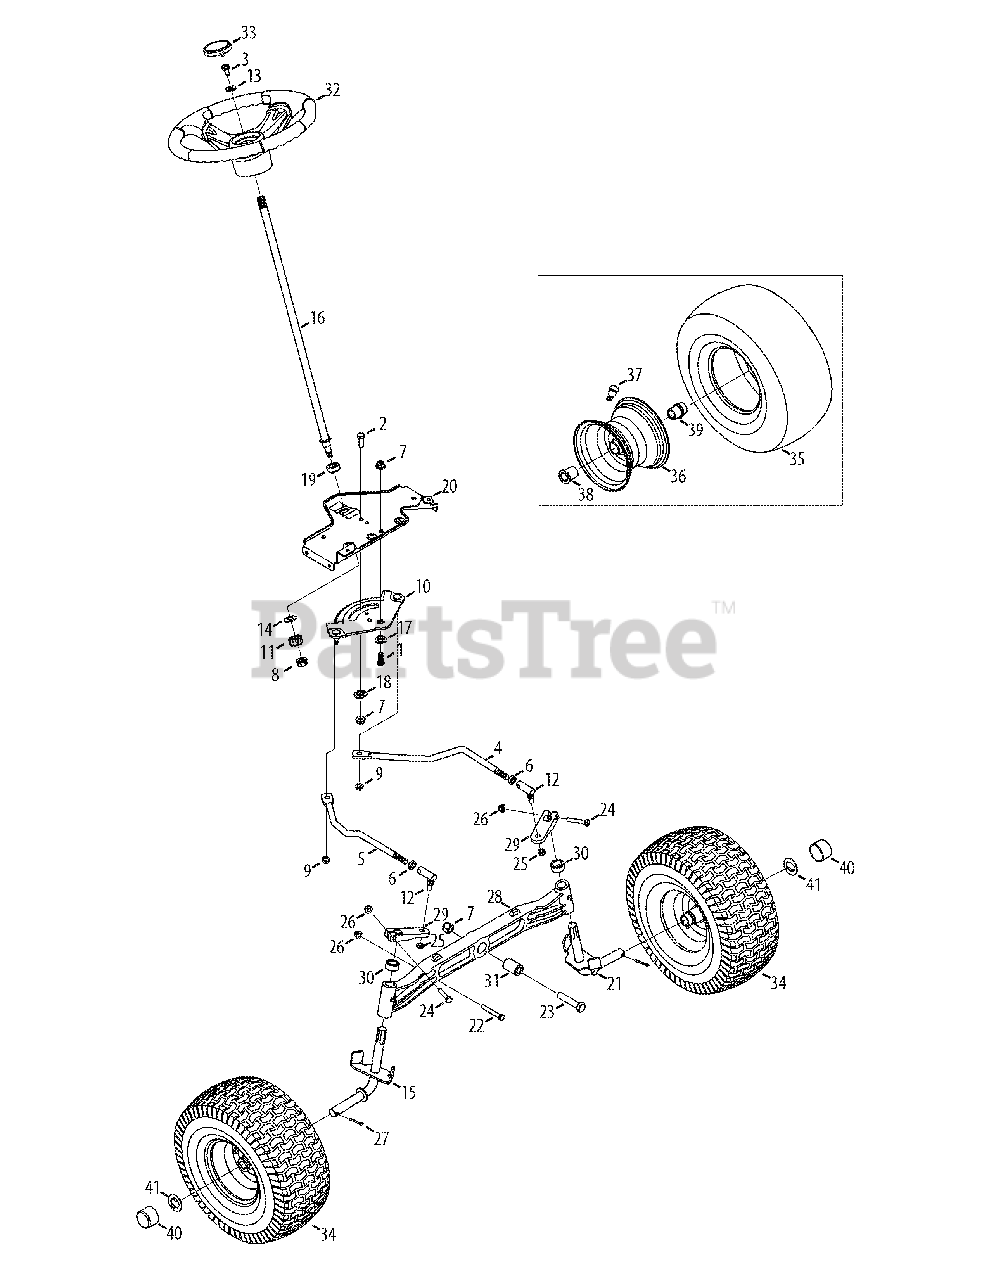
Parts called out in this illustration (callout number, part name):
1	Hex Screw, 3/8-16, 1.00, Gr5, Spec
2	Hex Screw, 3/8-16, 1.00, Gr5, Std
3	Hex Screw, 5/16-18, 1.00, Gr5, Lock
4	Link, Drag LH
5	Link, Drag RH
6	Nut, Jam, 7/16-20, Gr2
7	Nut, Flange Lock, 3/8-16, Grf,
8	Nut, Flange Lock, 7/16-20, Grb, Lock
9	Nut, Flange Lock, 5/16-18, Gr5, Sd Lk
10	Gear, Steering, 11/90 Ratio
11	Gear, Pinion, Steering
12	Ball Joint, 7/16-20, Lock
13	Washer, Flat, .406 x .875 x .105
14	Washer, Flat, .51 x 1.12 x .06
15	Axle Ass’y, RH .750 Dia (46" Deck)
16	Shaft, Steering, .625 OD x 24.25
17	Spacer, Shoulder, .385x 1.25 x .3025
18	Spacer, .38 x 1.375, Special
19	Bearing, Flange, Hex 5/8 Pm
20	Bracket, Support, Steering
20	Screw, .750 5/16-18
21	Axle Ass’y, LH .750 Dia (46" Deck)
22	Hex Screw, 5/16-18, 2.25, Gr5, Std
23	Hex Screw, 3/8-16, 2.50, Gr5, Std
24	Hex Screw, 5/16-18, 1.75, Gr5, Std
25	Nut, Hex Lock, 3/8-24, Grb
26	Nut, Flange Lock, 5/16-18, Grf
27	Pin, Cotter, 5/32, 1.25
28	Axle, Pivot Bar, Cast
29	Steering, Block
30	Spacer, .71 ID x .125 OD x .56
31	Spacer, .385 x 1.00 x 1.5075
32	Steering Wheel
33	Cap, Sprig, Small
34	Wheel Assembly
35	Tire, 15 x 6 x 6
36	Rim Assembly
37	Tubeless Air Valve
38	Flange Bearing, .760 x 1.00 x 1.20
39	Flange Bearing, .760 ID
40	Cap, Bumper
41	Washer, Flat, .350 x 1.559 x .062
